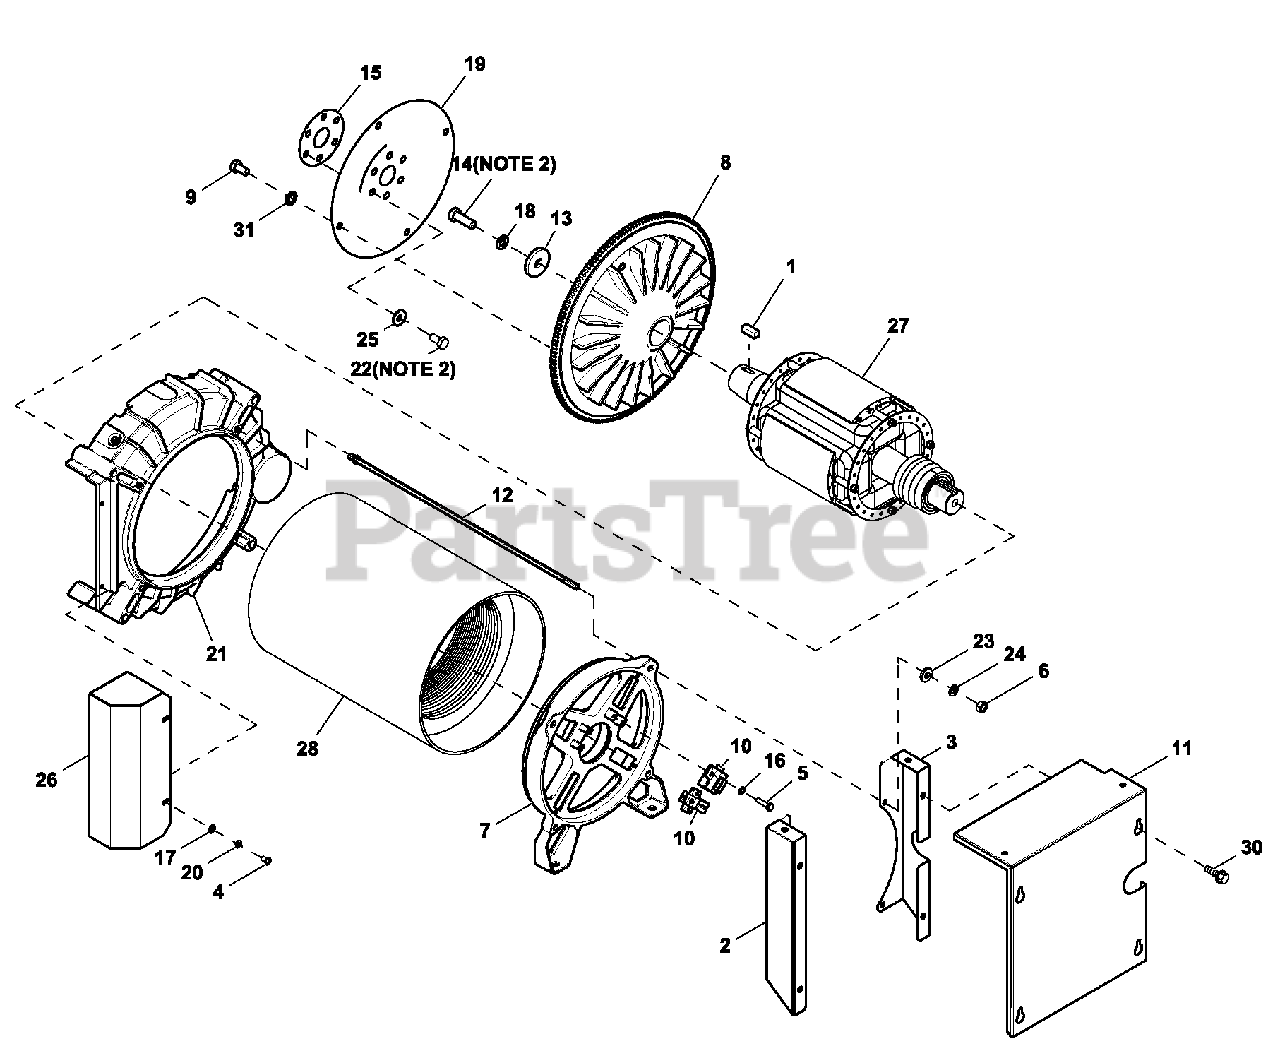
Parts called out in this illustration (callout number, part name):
1	KEY SQ 3/8 X 1 STEEL
2	SUPPORT LH ALT COVER
3	SUPPORT RH ALT COVER
4	SCREW PPHM M5-0.8 X 8 ZINC
5	SCREW HHC M4-0.7 X 16 C8.8
6	NUT HEX M8-1.25 G8 CLEAR ZINC
7	BEARING CARRIER REAR LG PILOT
8	FLYWHEEL ASSY 1.6L
9	SCREW HHFC M10-1.5 X 20 C8.8
10	HOLDER BRUSH - ASSEMBLY
11	COVER REAR 10" ALT
12	STUD M8-1.25 475 LONG (30KW)
13	SPACER ROTOR SHAFT
14	SCREW HHC M12-1.75 X 35 C8.8
15	PLATE SPACER 16GA 1.6L
16	WASHER LOCK INT #8
17	WASHER FLAT M5
18	WASHER LOCK M12
19	PLATE FLEX 1.6L R12.7
20	WASHER LOCK M5
21	HOUSING BLOWER
22	SCREW HHC M10-1.0 X 20 C10.9
23	WASHER FLAT .34ID X .75OD
24	WASHER LOCK M8-5/16
25	WASHER FLAT .41ID .94OD .12THK
26	BLOWER HOUSING SCREEN
27	ASSY RTR 25KW 2P (2006)
28	ASSY STR 102 25AD1 (2006)
30	SCREW HWHT M6-1 X 16 N WA Z/JS
31	WASHER LOCK M10 RIBBED ZINC
